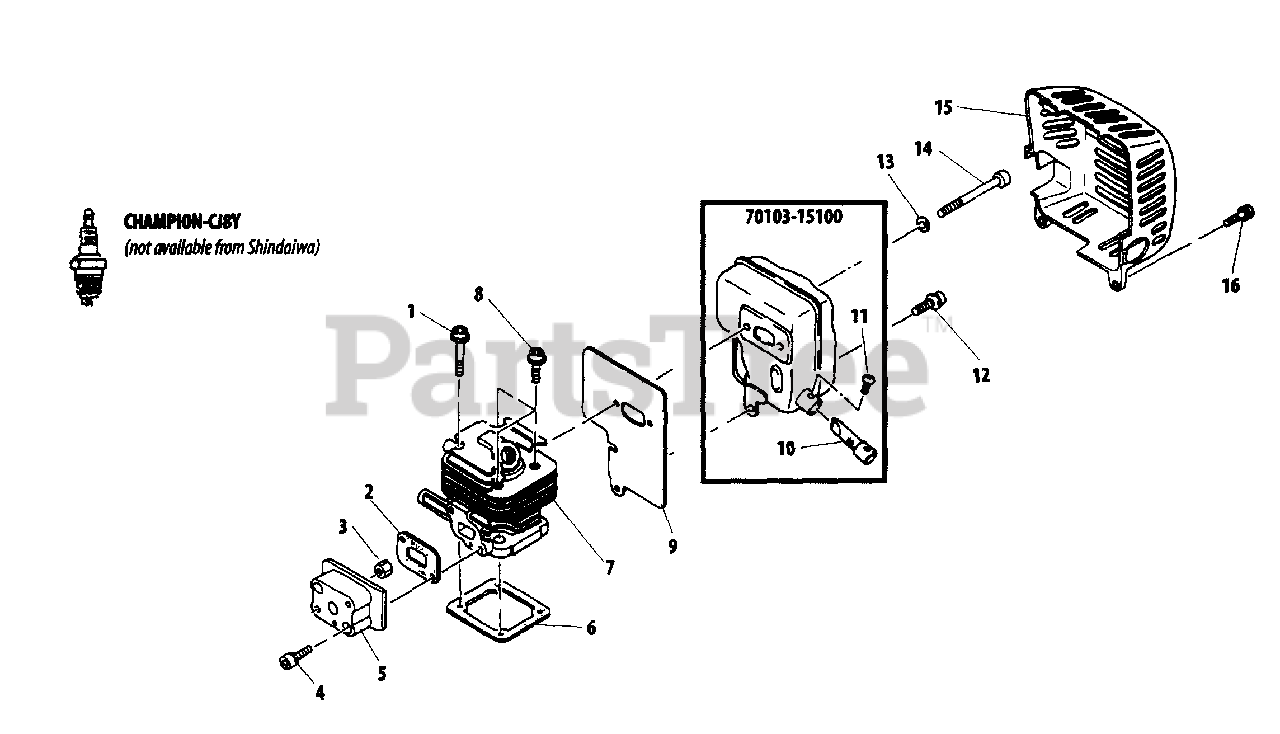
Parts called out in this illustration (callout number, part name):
1	BOLT
2	GASKET, INTAKE
4	BOLT M5×20
5	INSULATOR
6	GASKET, CYLINDER
7	CYLINDER
8	BOLT M5×16
9	GASKET, EXHAUST
10	SCREEN, SPARK ARRESTER
11	SCREW, TAPPING 3×6
12	BOLT M5×12
13	WASHER, FLAT 5.5×10×0.8
14	BOLT 5×55
15	COVER, MUFFLER
16	BOLT M5×16
